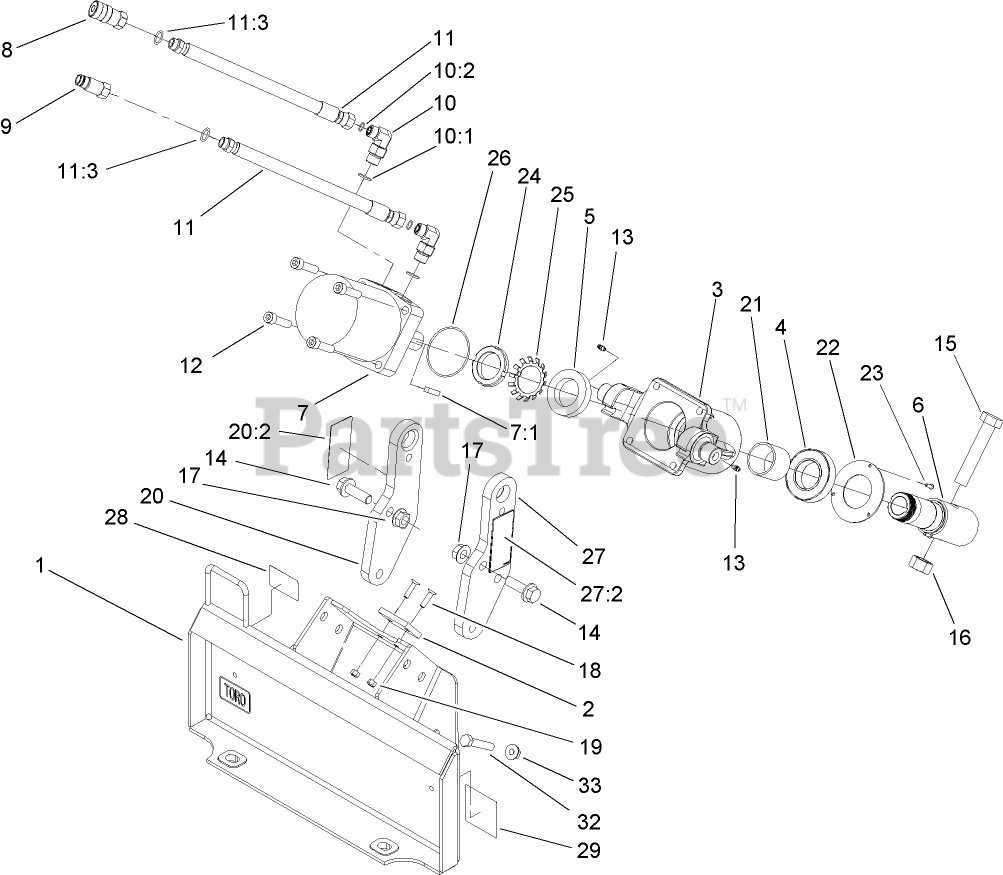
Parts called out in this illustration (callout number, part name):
1	FRAME ASM
2	PAD-STOP
3	AUGER HOUSING
4	BEARING
5	BEARING
6	SHAFT-AUGER
7	MOTOR-HYDRAULIC
8	COUPLER-FEMALE
9	NIPPLE-CONNECTOR
10	FITTING-ELBOW 90
10:1	O-RING
10:2	O-RING
11	HYD HOSE ASM
11:3	O-RING
12	SCREW-HSH
13	FITTING-GREASE
15	SCREW
16	NUT-HEX
17	NUT-FLANGE
18	SCREW-FH
19	NUT-LOCK, NI
20	PLATE-PIVOT, LH
20:2	DECAL-DANGER
21	SPACER-BEARING
22	PLATE-PROTECTOR, BEARING
23	SCREW-HSBH
24	NUT-BEARING
25	LOCKWASHER-BEARING
26	O-RING
27	PLATE-PIVOT, RH
27:2	DECAL-DANGER
28	DECAL
29	DECAL
32	SCREW-HH
33	NUT-HHF
